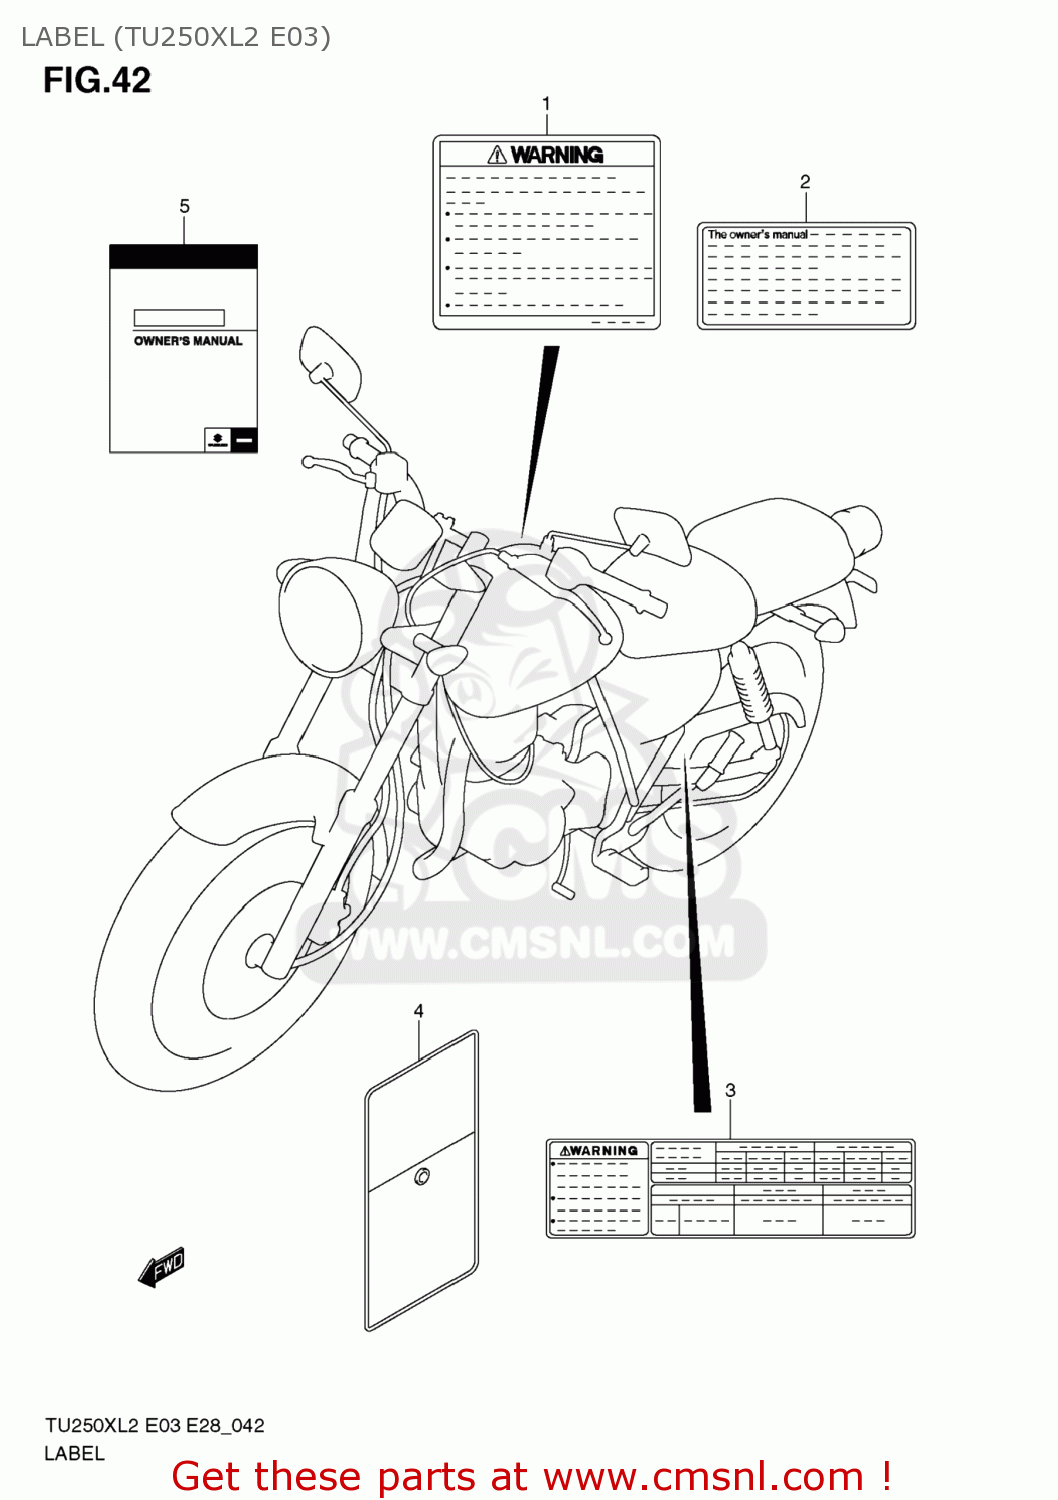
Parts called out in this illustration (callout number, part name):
1	LABEL,GENERAL WARNING
2	LABEL,MANUAL NOTICE
3	LABEL,TIRE INFORMATION
4	BAG,OWNER'S MANUAL
5	MANUAL,OWNER'S
